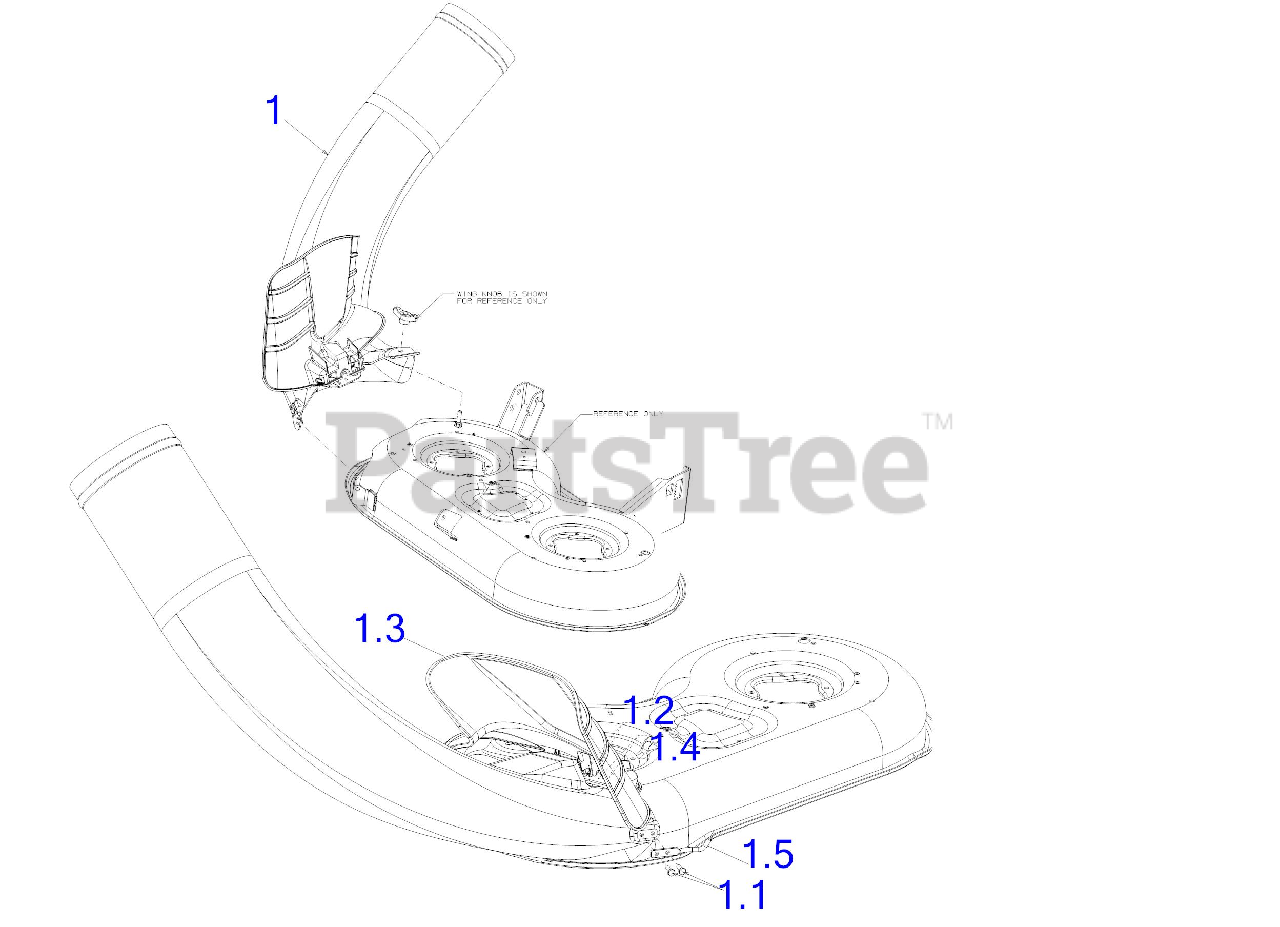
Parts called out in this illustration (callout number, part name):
1	34" LOWER BOOT ASSEMBLY
1.1	SCREW 1/4-20X.75 GR5
1.2	FLANGE LOCK NUT
1.3	DISCHARGE CHUTE
1.4	SPRING WASHER BELL
1.5	MULCH PLUG MOUTING ROD
